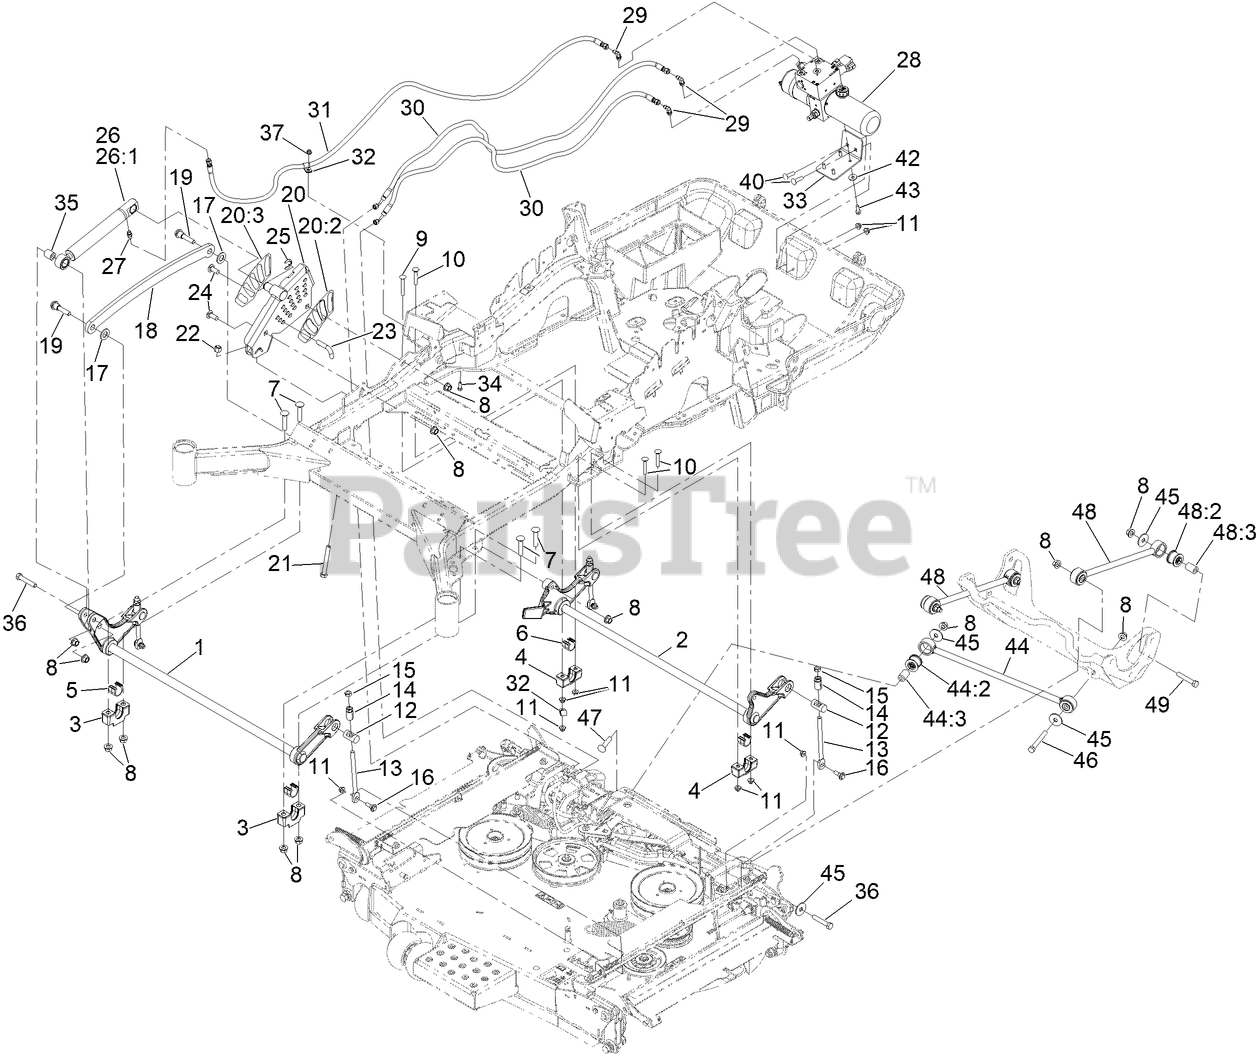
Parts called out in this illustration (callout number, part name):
1	DECKLIFT-FRONT
2	LIFT-DECK, REAR
3	SUPPORT-CROSS SHAFT, BEARING
4	SUPPORT-CROSS SHAFT, BEARING REAR
5	BEARING-CROSS SHAFT, FRONT
6	BEARING-CROSS SHAFT, REAR
7	BOLT-CARR
8	NUT-LOCK
9	SCREW-CARR
10	SCREW-CARR
11	NUT-HF, NI
12	TRUNNION
13	LINK-ADJUSTER, DECK LIFT
14	ADJUSTER-LIFT, DECK
15	NUT-JAM
16	SCREW-SHOULDER, HHF
17	WASHER-FLAT
18	LINK-LIFT, DECK
19	SCREW-HHF, SHOULDER
20	HOC ASM
20:2	DECAL-HEIGHT OF CUT
20:3	DECAL-HEIGHT OF CUT, OUTER
21	BOLT-TAP
22	NUT-LOCK, NI
23	PIN-HOC
24	SCREW-CARR, SHORT NECK
25	RING-RETAINING
26	CYLINDER-LIFT
26:1	KIT, CYL REPAIR
27	Adapter, Straight
28	POWER UNIT
29	Adapter, 90?
30	HOSE-HYD, HP
31	HOSE-HYD, HP
32	R-CLAMP
33	MOUNT-POWER UNIT
34	SCREW-HH
35	SPACER-PIVOT
36	SCREW-HH
37	NUT-HF, NI
40	SCREW-CARR
42	WASHER-SPRING
43	SCREW-HHF
44	PANHARD ROD ASM
44:2	BUSHING-SUSPENSION, RUBBER
44:3	SPACER
45	WASHER-THRUST
46	SCREW-HH
47	SCREW-CARR
48	ASM, DECK STRUT
48:2	BUSHING-RUBBER
48:3	SPACER
49	SCREW-HH
